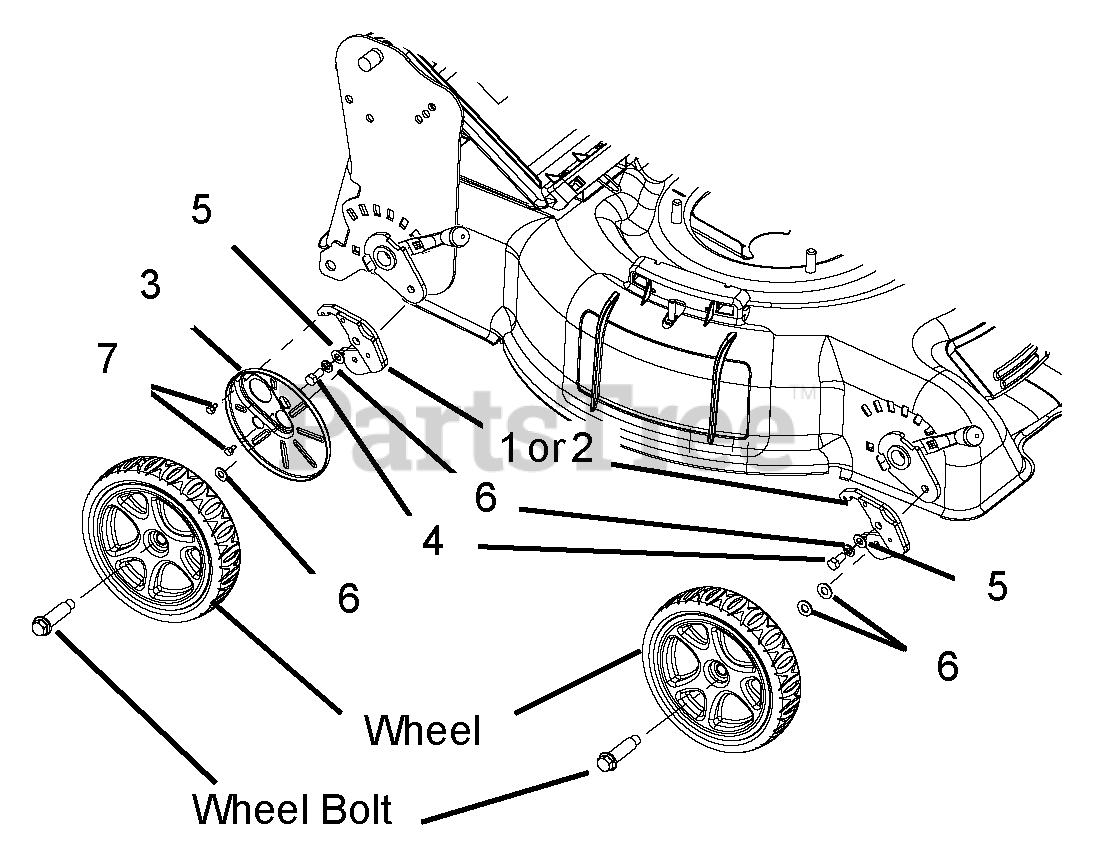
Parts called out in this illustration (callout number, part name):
1	BRKT, FLORIDA HOC EXT LH
2	BRKT, FLORIDA HOC EXT RH
3	WHEEL COVER, HOC EXT KIT
4	@BLT-HEX .38-16X.75 GR5 YWZC
5	@WSHR-LK .38X.094 REG YWZC
6	@WSHR-FL-STL.406X.812X.065 YWZ
7	@SCR-TAP 10-24X.375 HWH YZ TR
